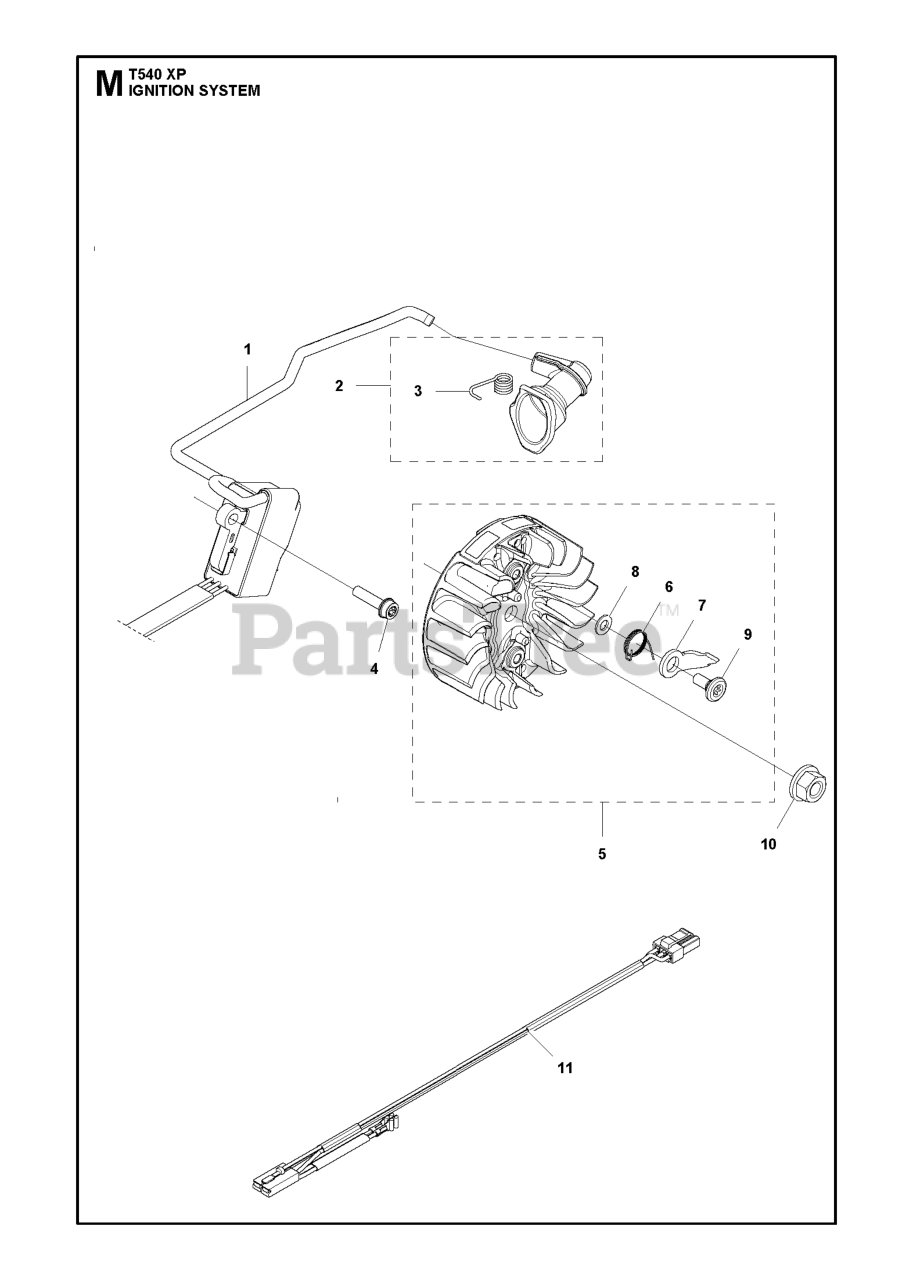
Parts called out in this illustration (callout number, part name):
1	IGNITION MODULE
2	SPARK PLUG CAP ASSY
3	SPRING
4	SCREW ITXSCFM
5	FLYWHEEL ASSY
10	NUT W/ WASHER
11	WIRING ASSY
